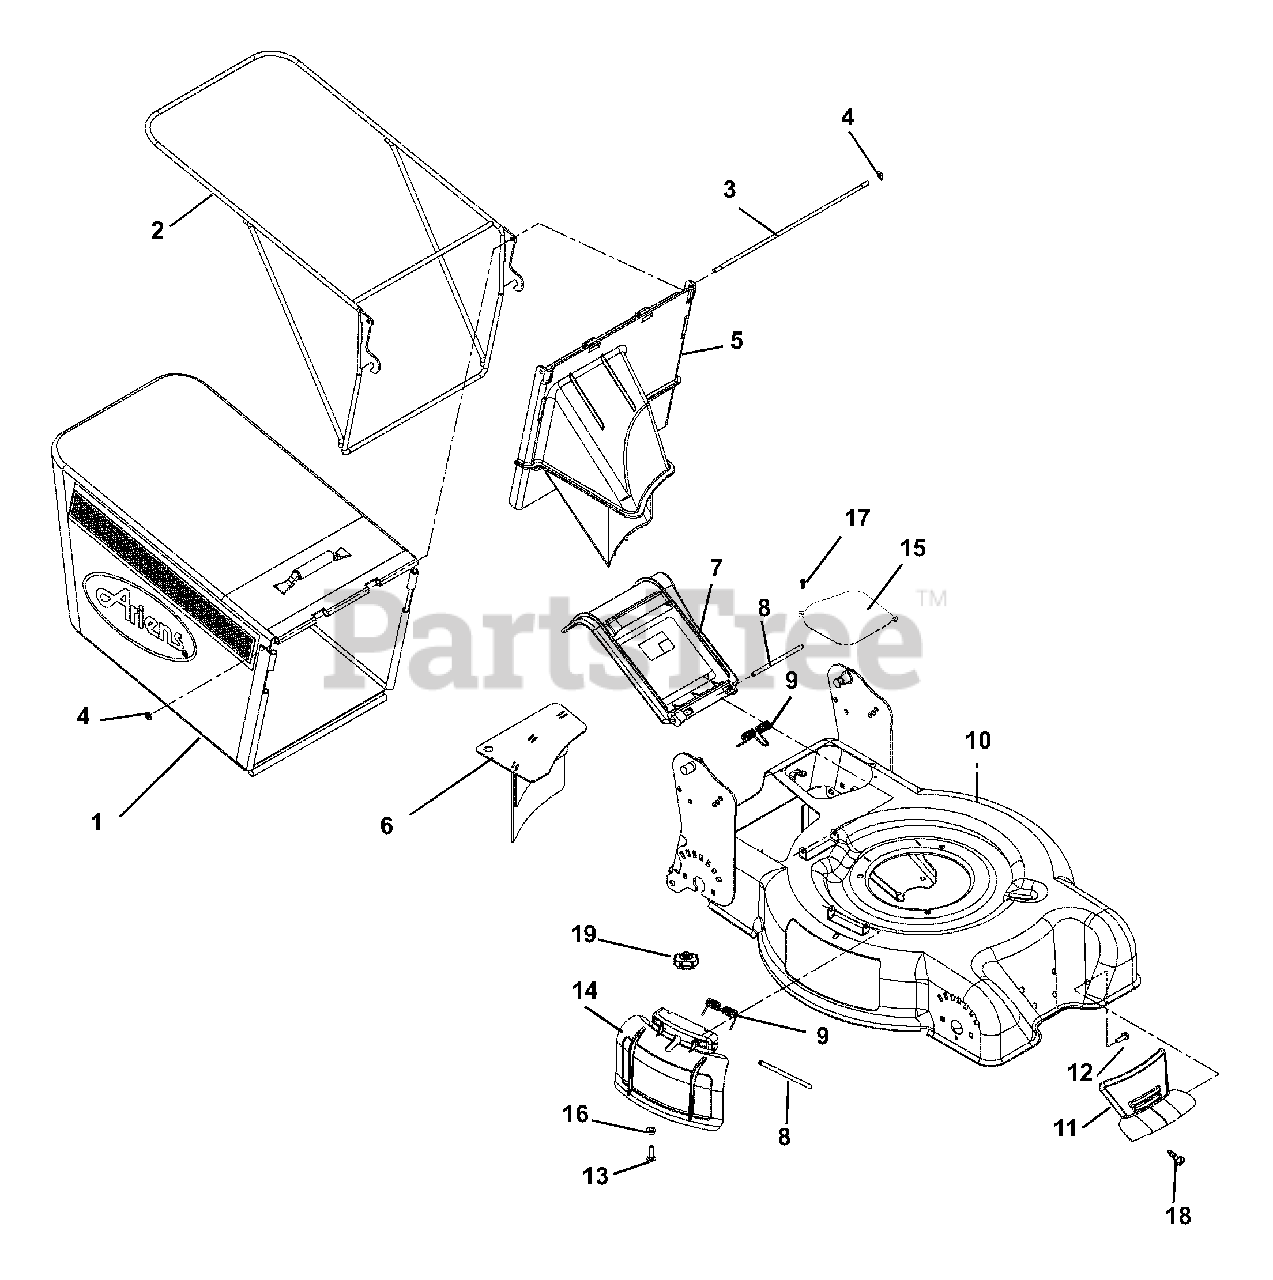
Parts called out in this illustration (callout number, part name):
1	WBLM, Gravley Bagger
2	Frame, Bagger
3	Rod, Hinge
4	Nut, Push .25 x .50 O.D.
5	Bagger Door
6	Mulch Plug
7	Rear Discharge Cover
8	Pin, Hinge
9	Spring, Torsion
10	21" Deck Weldment
11	Grill Insert
12	Screw, Tapping 12-12 x .75
13	Bolt, Round Head Square Neck .25-20 x .75
14	Mulch Cover
15	Cover, Transmission Access
17	Screw, Tapping 10-24 x .375 Hex Washer Head Thread Rolling
18	Screw, Self Drill/Tap
19	Knob, Clamping, .250-20 Nyloc
